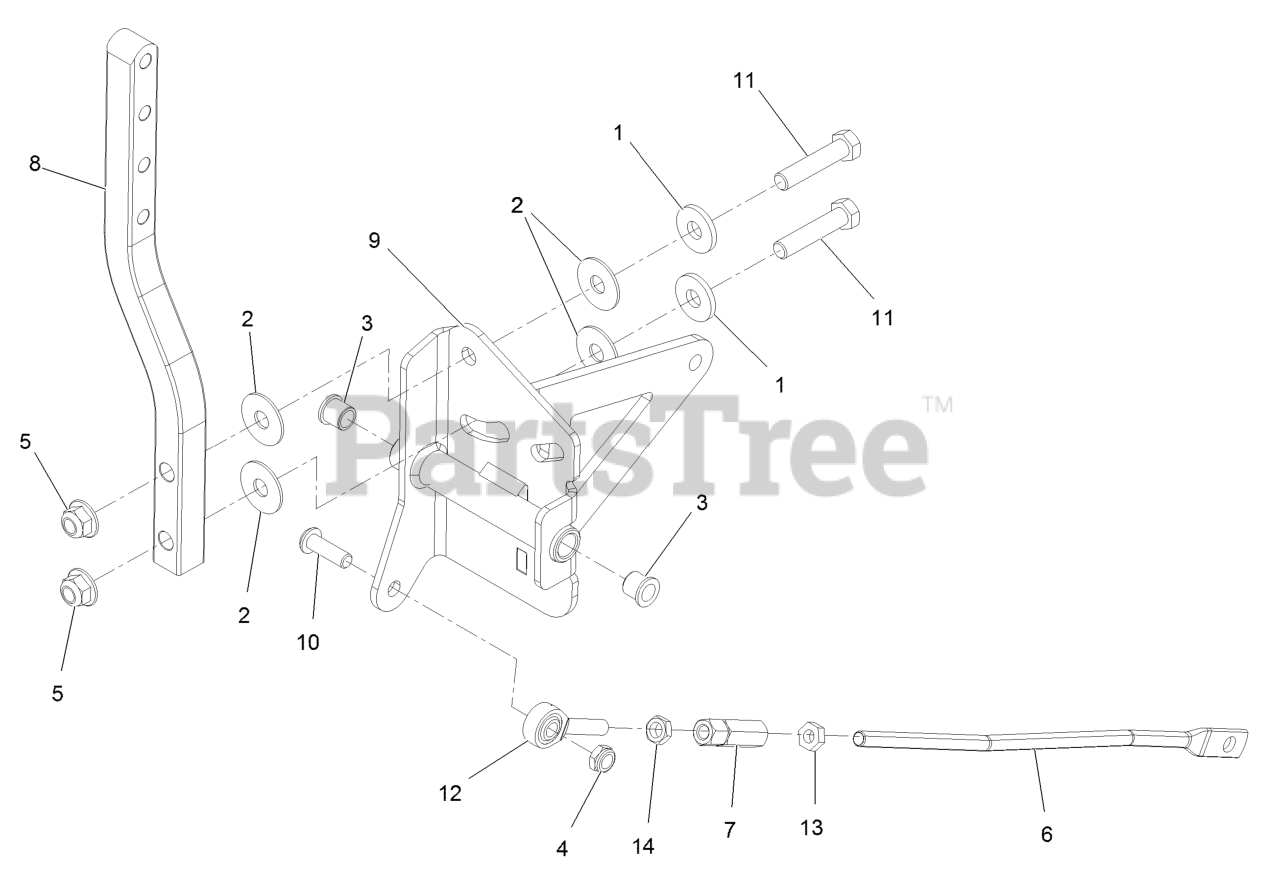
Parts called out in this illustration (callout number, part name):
1	WASHER
2	WASHER-PLASTIC
3	BEARING
4	NUT-LOCK, NI
5	NUT-HF, NI
6	LINK,MOTION CONTROL
7	NUT-ROD ADJUSTMENT
8	ARM-MOTION CONTROL
9	RH CONTROL PIVOT ASM
10	SCREW-HSBH
11	SCREW-HH
12	BEARING-ROD END, LH
13	NUT-JAM
14	NUT-JAM
